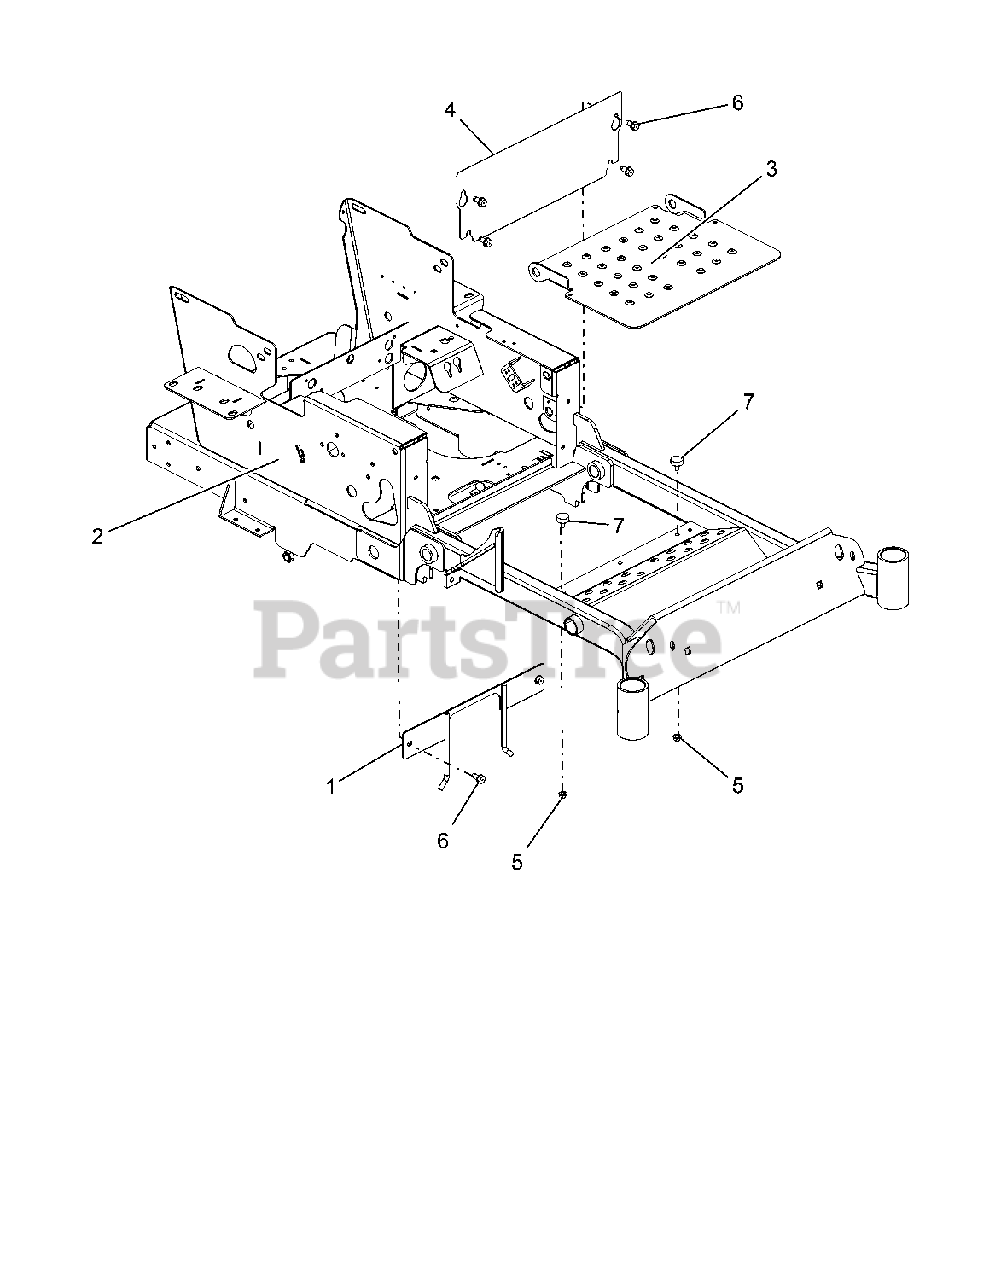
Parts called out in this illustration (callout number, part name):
1	WLDMT, PTO BELT FINGER-BLACK
2	WLDMT, 44"-48" HD FRAME (BLACK)
3	PANEL, INSPECTION
4	PLATE, KICK (RED)
5	@NUT-SPNLK-FLG .312-18 YWZC
6	SCR-TAP .38-16X.75 HWH TR YWZ
7	BUMPER, RUBBER
